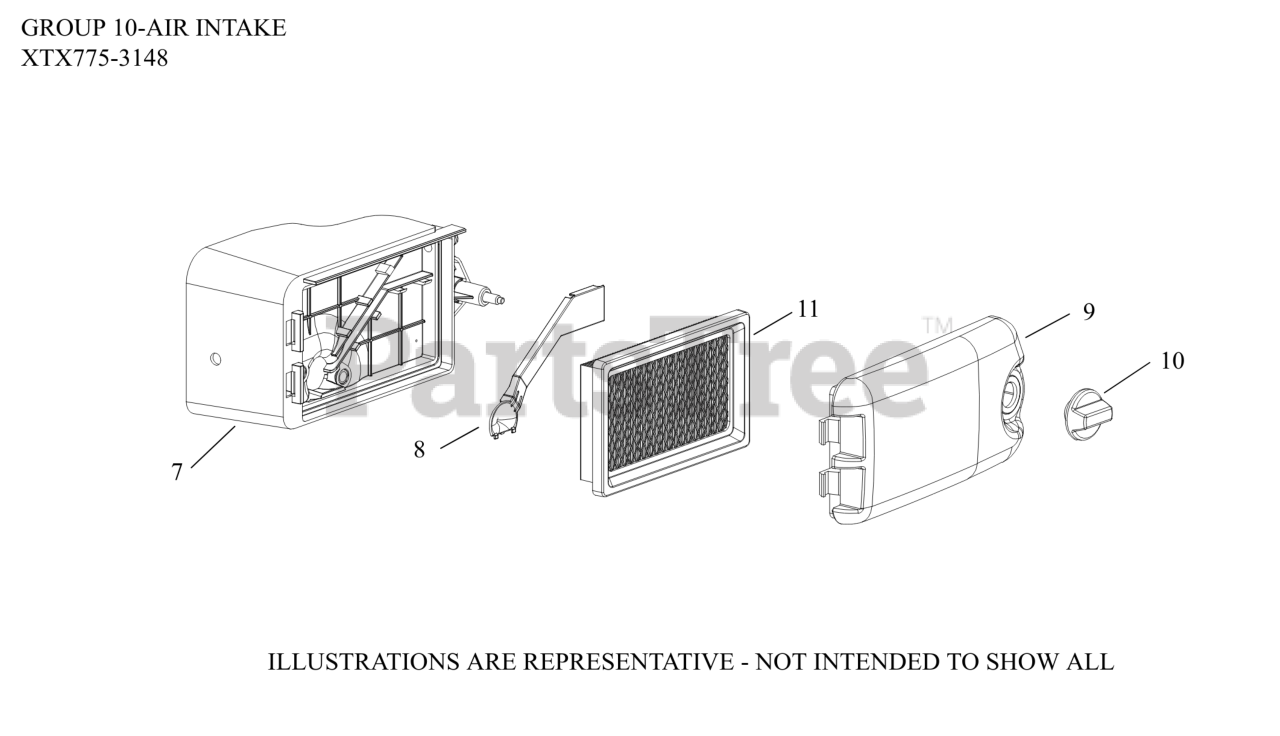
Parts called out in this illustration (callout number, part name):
7	AIR CLEANER BASE-USE 14 094 23-S
8	COVER, A/C BASE (BREATHER GAS)
9	COVER, AIR CLEANER
10	KNOB-USE 14 341 07-S
11	ELEMENT, AIR FILTER
